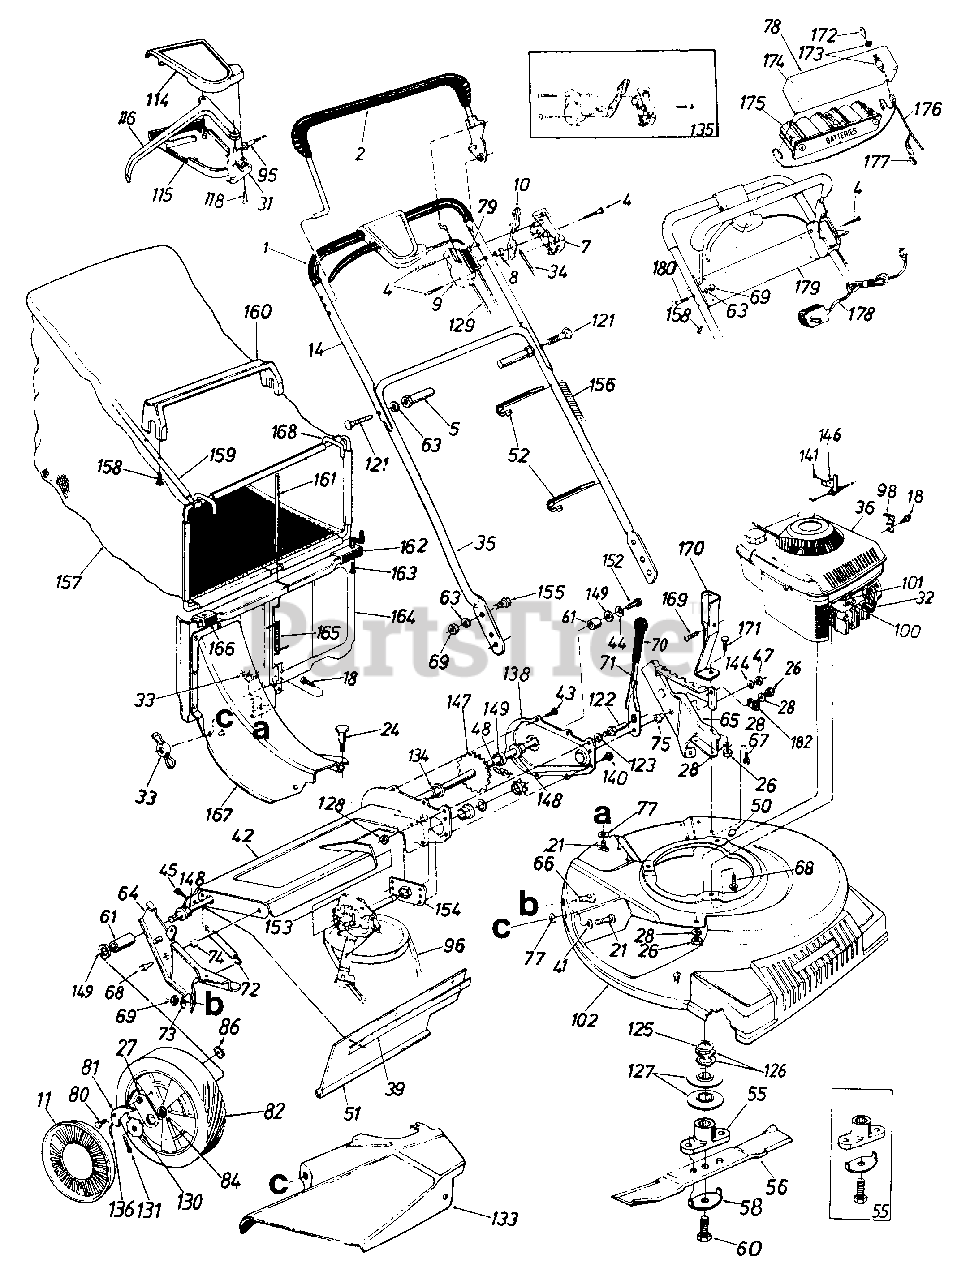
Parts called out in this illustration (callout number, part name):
1	Grip
2	Control Handle Ass'y. L.H.
4	Truss Mach. Scr. #12 x 1.50" Lg.
5	Catcher Support Pin
7	Control Panel Half
8	Control Disc Pin
9	Clutch Panel Half
10	Throttle Control Lever
11	Hub Cap
14	Upper Handle
18	Hex B-Tap Scr. #10 x .38"
21	Carriage Bolt 1/4-20 x .62"
24	Shoulder Bolt .312 Dia. x .18 Lg. Special
26	Hex Nut 1/4-20 Thd.
27	Pawl Plate
28	L-Wash. 1/4" I.D.
31	S.P. Control Cover
32	Spark Plug Insulator
33	Wing Nut
34	Throttle Control Wire 58"
35	Lower Handle
36	Engine
39	Retaining Strip
41	Fl-Wash. .344" I.D. x .62"
44	Bell-Wash. 1/41' I.D.
45	Hex AB-Tap Scr. 1/4 X .6211
47	Hex Patch L-Nut 3/8-24 Thd.
48	#48 Chain .500" Pitch x .30 Links
51	Rear Flap 3.75" x 17.30" Lg.
52	Cable Tie
55	Blade Adapter Kit
56	21" Blade
58	Blade Bell-Wash. .45" I.D.
60	Hex Bolt 7/16-20 x 1.5"
61	Spacer.513" I.D.
63	L-Wash. 5/16" I.D.
64	R.H. Handle Wheel Brkt. Ass'y.
65	L.H. Handle Wheel Brkt. Ass'y.
66	Carriage Bolt 5/16-18 x .62"
67	Hex Wash. Hd. B-Tap Scr. 5/16-18
68	Hex Wash. Hd. TT-Tap Scr. 3/8-16
69	Hex Nut 5/16-18 Thd.
71	Height Adj. Lever
72	Extension Spring 3.80" Lg.
73	Bell-Wash. 5/16" I.D.
74	Spacer.383" I.D.
75	Shld. Spacer .5" Dia.
77	Bolt Retainer 1/4 X .501 O.D.
78	Instruction Label
79	Control Label
80	Shld. Scr. .342" Dia. x .268
81	Pawl
82	Wheel Ass'y. Comp. Rear
84	Sleeve Bearing 1/2" I.D.
86	Flat Nut 1/4-20 Thd.
95	S.P. Cable x 50" Lg.
96	"V"-Belt
98	Casing Clamp
100	Hex B-Tap Scr. #10 x .62"
101	Casing Clamp
115	Self-Propelled Control Cover
116	Control Lever
118	Fl-"C"-Sunk Hd. Tap Scr. #10 x .75" Lg.
121	Curved Carr. Bolt 5/16-18 x 1.75" Lg.
122	Shld. Pin 1.43" Lg.
123	L-Wash. 3/8" I.D.
125	Serrated Wash. 1.0" I.D.
126	Wave Wash. 1.005" I.D.
127	Serrated Pulley Half
128	Hex Jam Nut 3/8-24 Thd.
129	Control Cable 46"
130	Ratchet Wheel 1.62" O.D.
131	Cotter Pin 1/8" Dia. x 1"
133	Side Chute Deflector Ass'y.
134	Flange Bearing
135	Kit Control Housing Comp.
136	Spring Nylon
141	Pop Rivet
144	Fl-Wash. .385" I.D. x .87"
146	Cable Bracket
147	Rear Shaft Ass'y. 21.94" Lg.
148	Hex Flange Brg. .506" I.D.
149	Fl-Wash. .531" I.D. x .930"
152	Hex Bolt 1/4-20 x .62" Lg. (Grade 5)
153	Transmission Comp.
154	Hex Bearing Cup
155	Truss Mach. Scr. 5/16-18 x .75" Lg.
156	Plastic Tubing
157	Grass Bag
158	Hex AB-Tap Scr. #12 x 1.25" Lg.
159	Rear Catcher Frame
160	Bag Handle
161	Chute Rod .188" Dia.
162	Door Clip
163	Hex AB-Tap Scr. 1/4 x .75" Lg.
164	Chute Door
165	Torsion Spring
166	Panel Clip
167	Top Discharge Chute Ass'y.
168	Front Catcher Frame
169	Truss Mach. Scr. 1/4-20 x .50" Lg.
170	Grass Catcher Bracket
171	Hex Bolt 1/4-20 x .50" Lg.
172	Ignition Key
173	Ignition Switch
174	Battery Tray
175	Battery Pack
176	Wire Harness
177	Plug
178	Battery Charger
179	Lower Battery Tray
180	Curved Carr. Bolt 5/16-18 x 1.38" Lg.
182	Clamp
